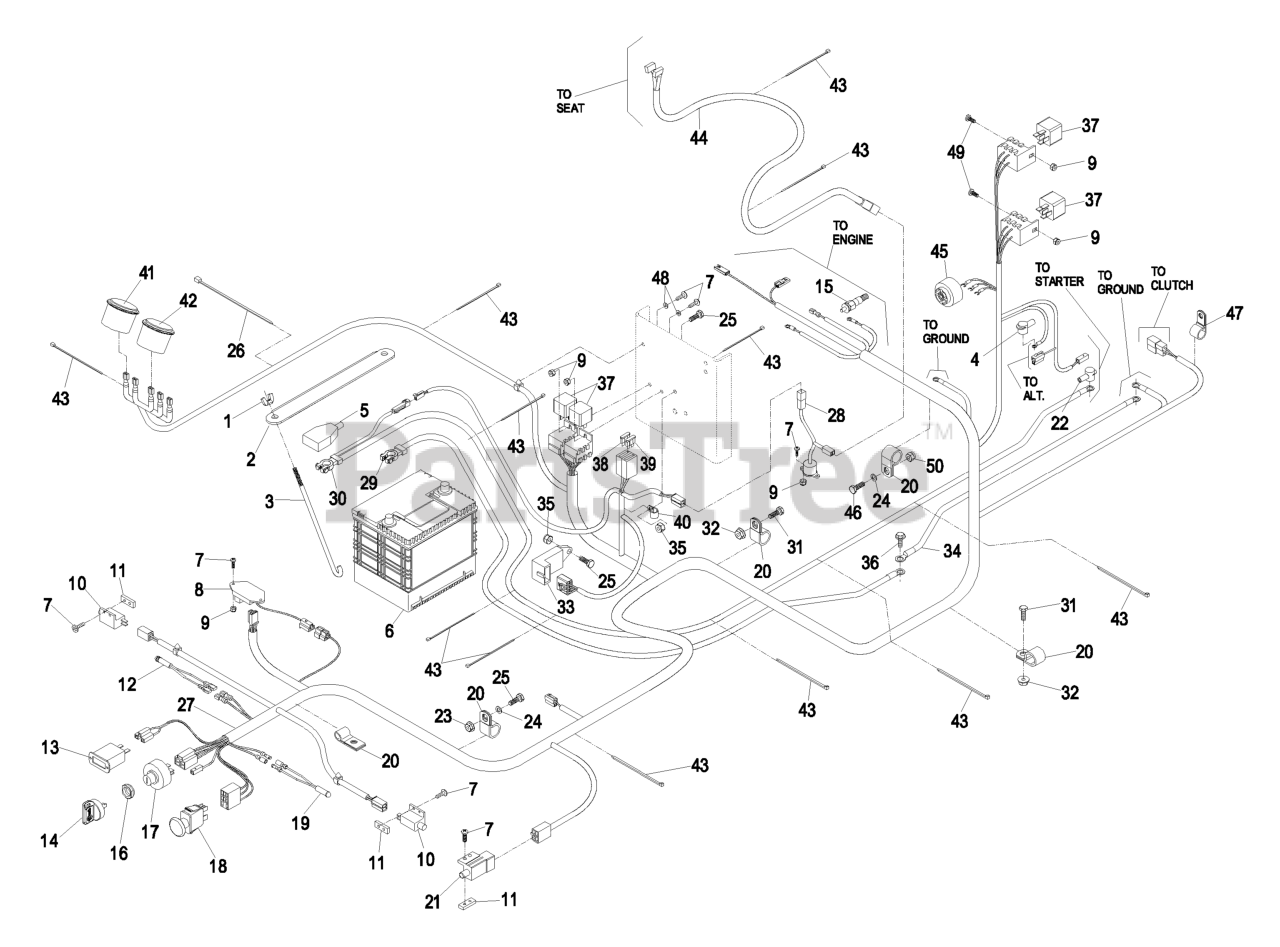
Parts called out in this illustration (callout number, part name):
1	WINGNUT
2	HOLDDOWN-BATTERY
3	BOLT-HOLDDOWN
4	CAP-INSULATOR, RED
5	INSULATOR-TERMINAL, BATTE
6	Battery, 12v SAE Post
7	SCREW-PPH
8	MODULE-DELAY, SEAT
9	NUT-LOCK, NI
10	SWITCH-OPEN, NORMALLY
11	PLATE-TAPPED
12	INDICATOR-LED, RED
13	METER-HOUR
14	KEY-IGNITION
15	SENDER-TEMPERATURE
16	NUT-SWITCH, IGNITION
19	INDICATOR-LED, AMBER
20	CLIP-LOOM
22	INSULATOR-STARTER
24	WASHER-FLAT
25	SCREW-HH
26	TIE-PLASTIC
27	Harness, Wiring
29	CABLE-BATTERY NEGATIVE
30	CABLE-STARTER
31	SCREW-HH
33	Briggs & Stratton P/N 820373 Module, Pre-Heat Timer
34	CABLE-ENGINE NEGATIVE
35	NUT-LOCK, NI
36	Screw-HWH 5/16-18 X 3/4 Tf
38	FUSE-BLADE TYPE, 20 AMP
39	FUSE-40 AMP
40	CLIP-LOOM
41	GAUGE-VOLTMETER
42	GAUGE-TEMPERATURE
43	TIE-PLASTIC
44	HARNESS-WIRING, SEAT
45	ALARM-TONE, DUAL
46	SCREW-HH
47	CLIP-LOOM
48	WASHER-FLAT
50	NUT-LOCK
